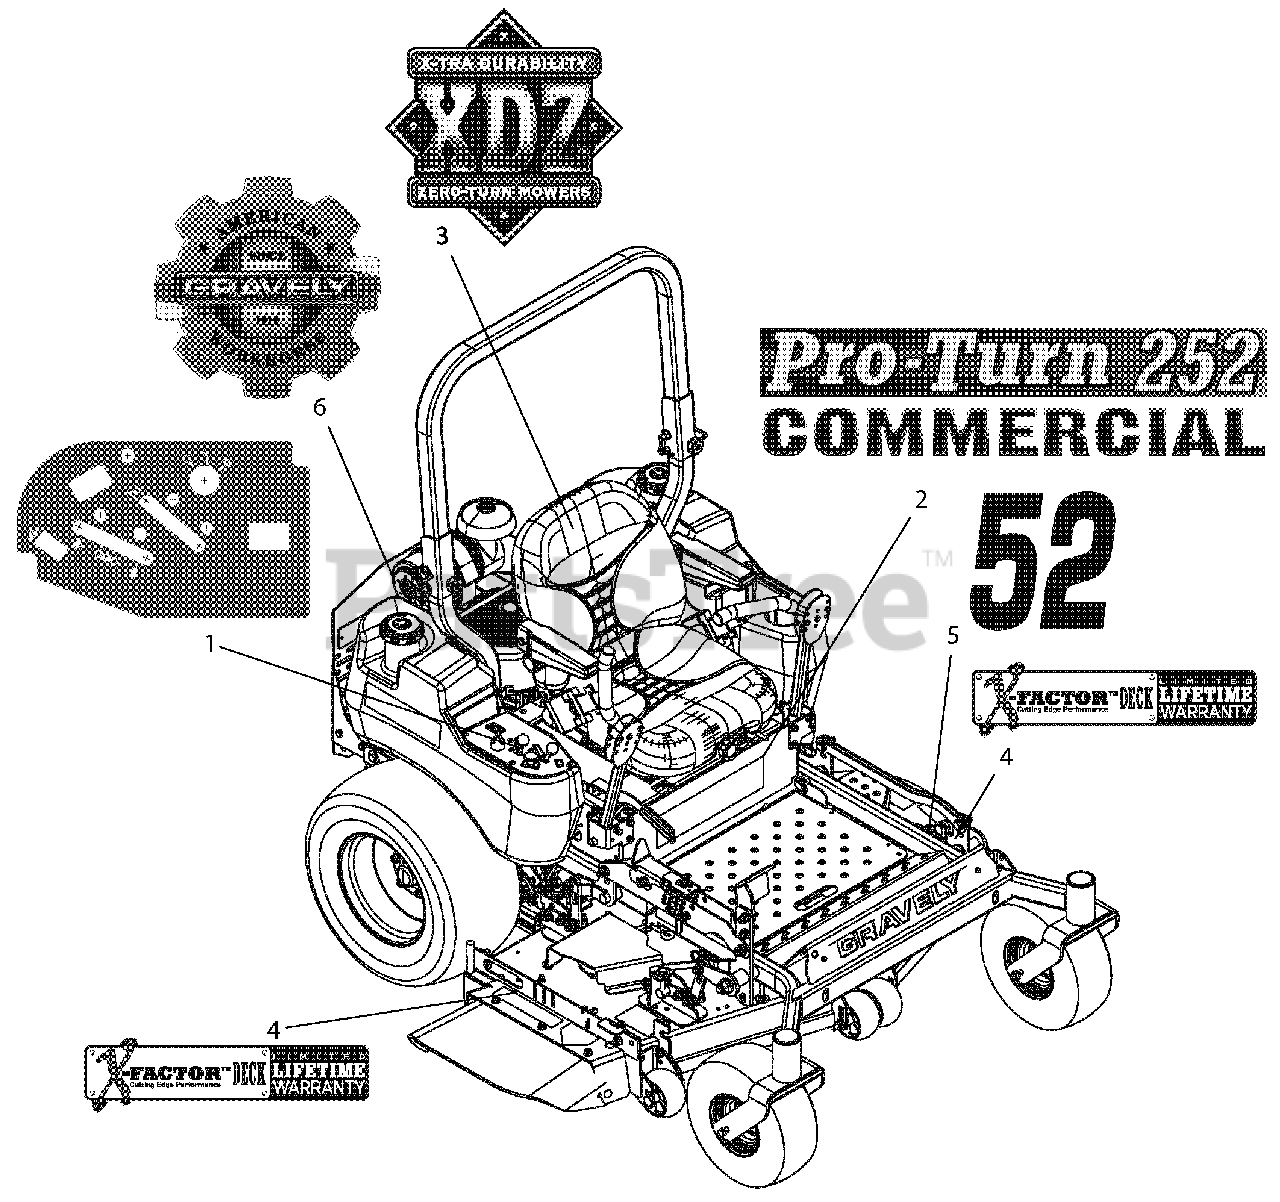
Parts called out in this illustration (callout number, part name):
1	DECAL, CONTROL PANEL
2	DECAL, PROTURN 252
3	DECAL, XDZ
4	DECAL, X-FACTOR DECK
5	DECAL, 52"
6	DECAL, GRAVELY HERITAGE-LARGE
